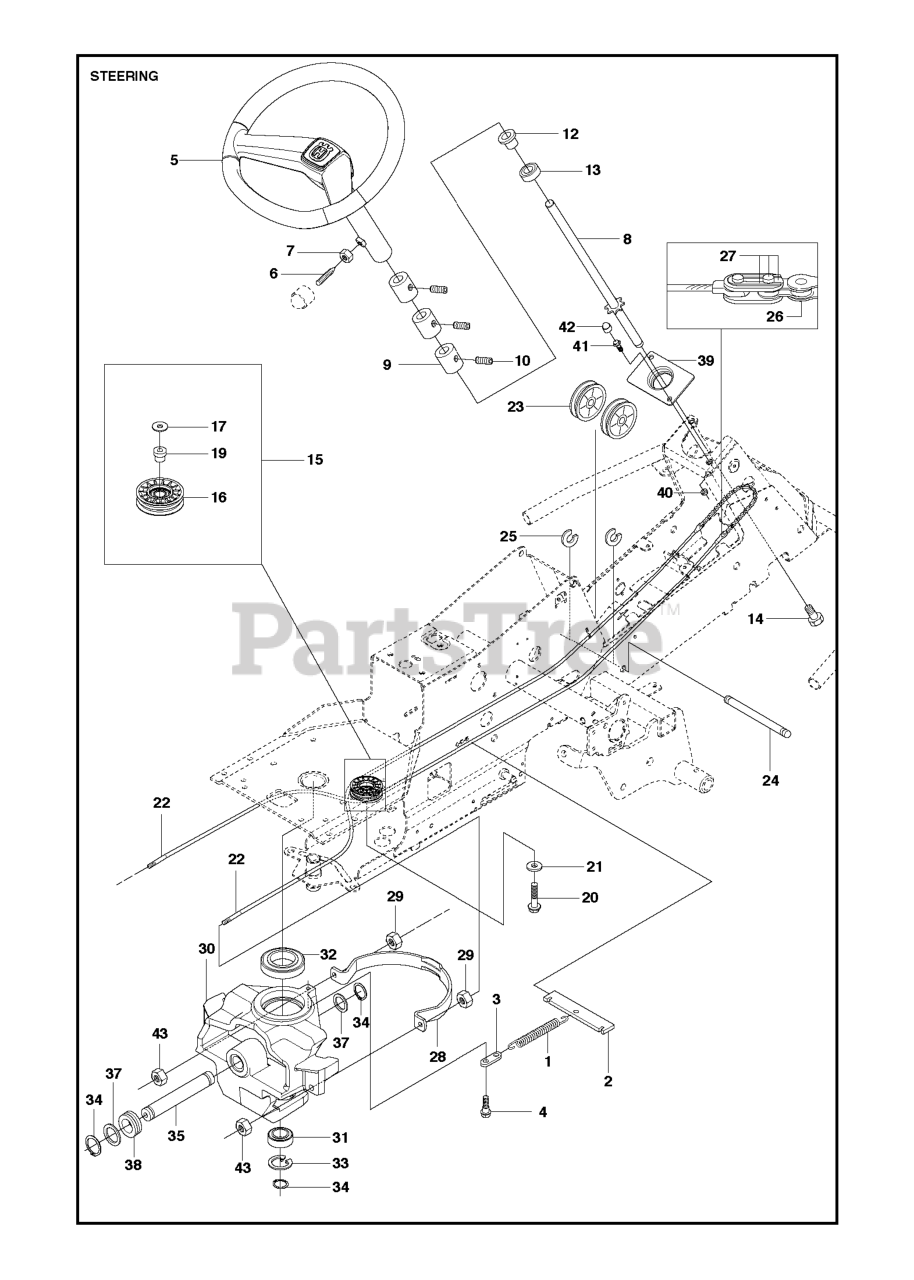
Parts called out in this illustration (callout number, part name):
2	SPRING BRACKET
5	STEERING WHEEL
7	NUT
8	STEERING ROD
9	SPACER
13	BALL BEARING 6004-2RS1
17	CIRCLIP SGH 47
20	COLLAR SCREW
22	WIRE ASSY
25	RETAINING RING
26	STEERING CHAIN
28	WIRE GUIDE
29	NUT
31	Ball Bearing 6005-2rs
32	BALL BEARING 6010 2RS1
33	CIRCLIP SGH 47
34	RETAINING RING SGA 25
40	NUT
41	COLLAR SCREW
42	PROTECTIVE COVER
43	NUT
